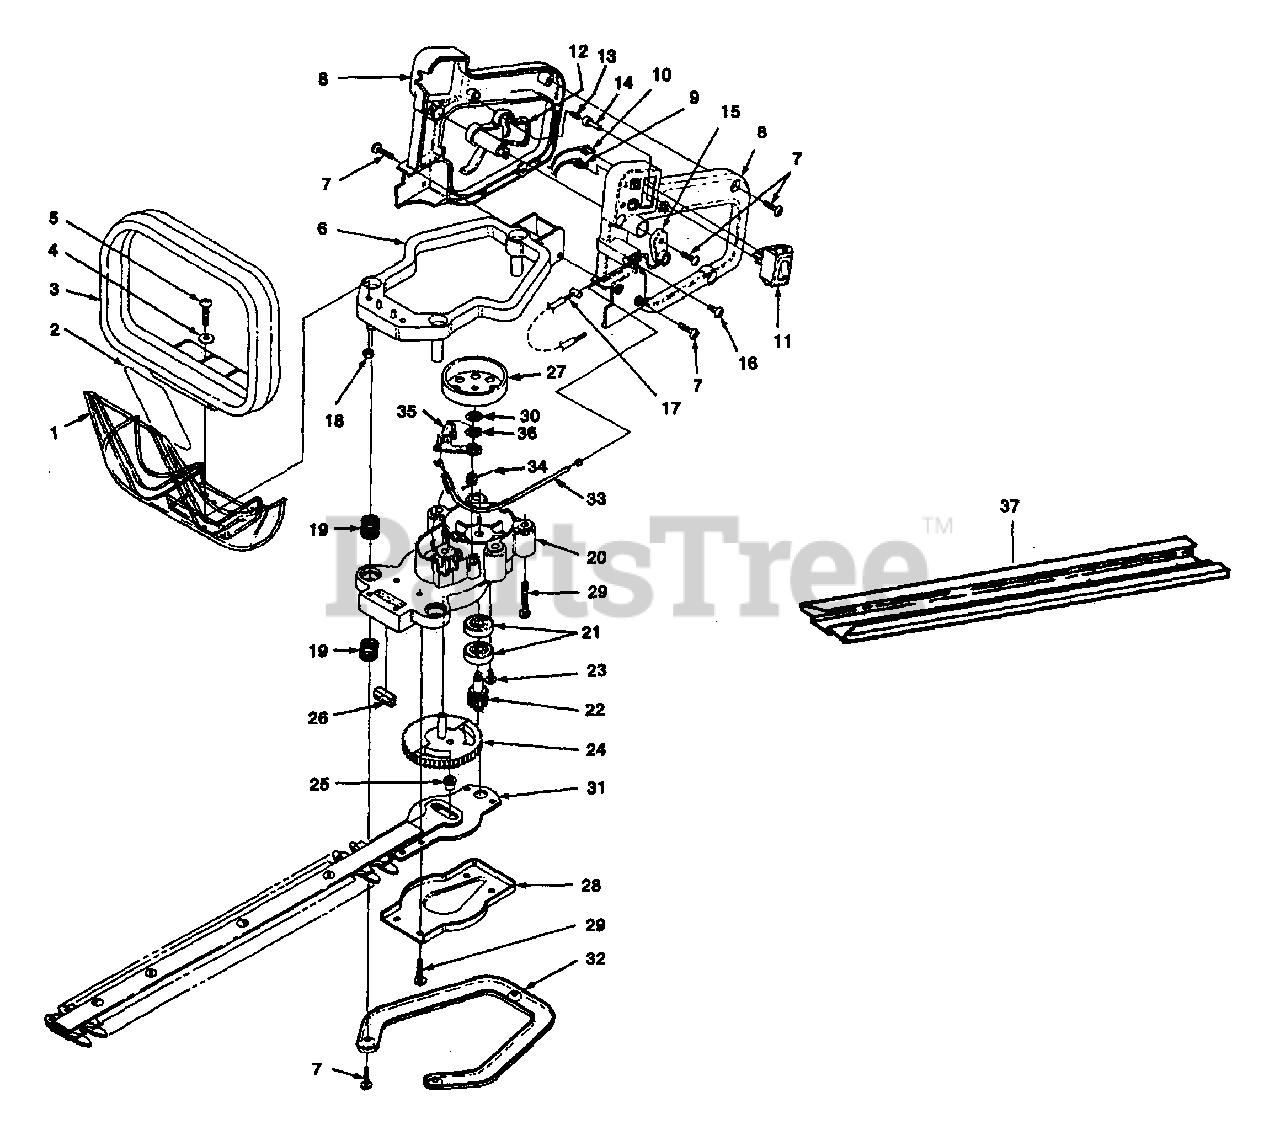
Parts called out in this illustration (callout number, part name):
1	GUARD-Hand
2	DECAL-Caution
3	HANDLE-Front
4	WASHER-Flat (10-24)
5	SCREW-Thread Form. (10-24 x 3/4 )
6	BASE-Vibration Isolator
7	SCREW-Thread Form. (#8 x 3/4")
8	HANDLE Assembly
9	LEAD-Electrical
10	LEAD-Ground
11	SWITCH
12	TRIGGER
14	BUTTON-Lock
15	LEVER, Trigger
16	SCREW-Thread Form. (#10 x 1/2")
17	CABLE-Throttle
18	NUT-Hex (10-24)
19	SPRING-Compression
20	GEAR BOX ASSEMBLY
21	BEARING-Ball
22	PINION & SCREW ASSEMBLY
23	SCREW-Thread Form. (#10 x 1/2")
24	GEAR & PIN ASSEMBLY
25	BUSHING
26	BLADE-Seal
27	DRUM-Clutch
28	COVER-Gear Box
29	SCREW-Thread Form. (#10 x 7/8")
31	BLADE ASSY. (17")
34	SPRING-Torsion
35	BRAKE ARM
36	PUSH NUT
37	GUARD-Blade (17")
